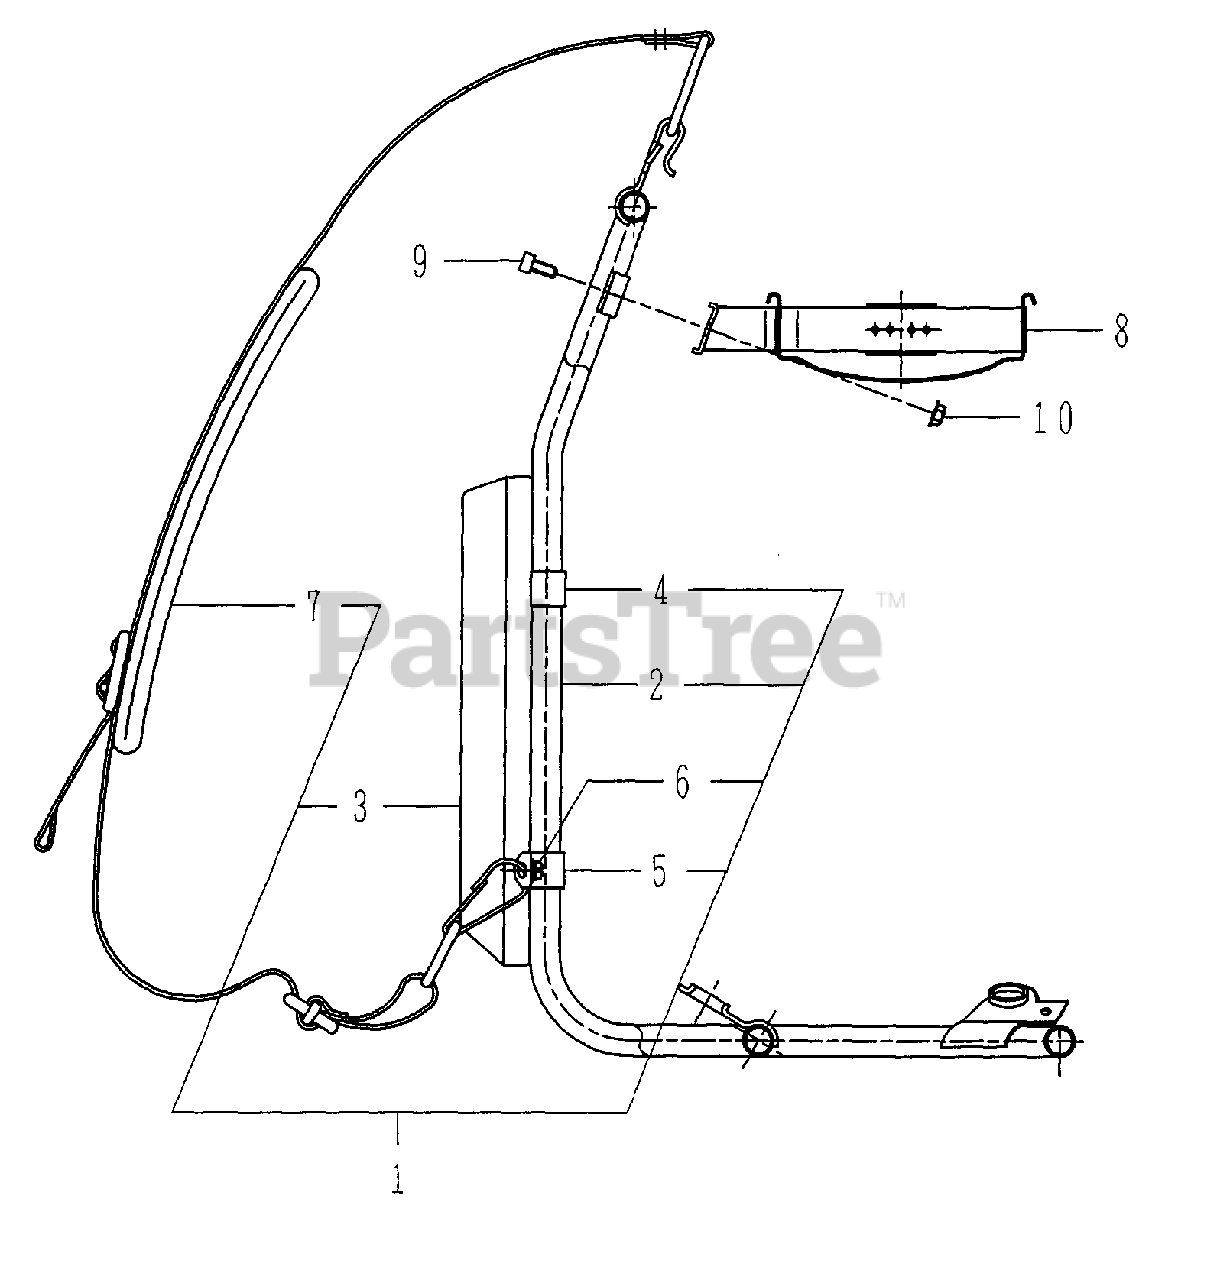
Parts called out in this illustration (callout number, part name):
1	FRAME ASSY, BACKPACK
2	FRAME, BACKPACK
3	PAD
4	CLAMP, UPPER
5	CLAMP, LOWER
6	SCREW
7	HARNESS ASSY
8	BRACKET, FUEL TANK
9	BOLT
10	NUT
